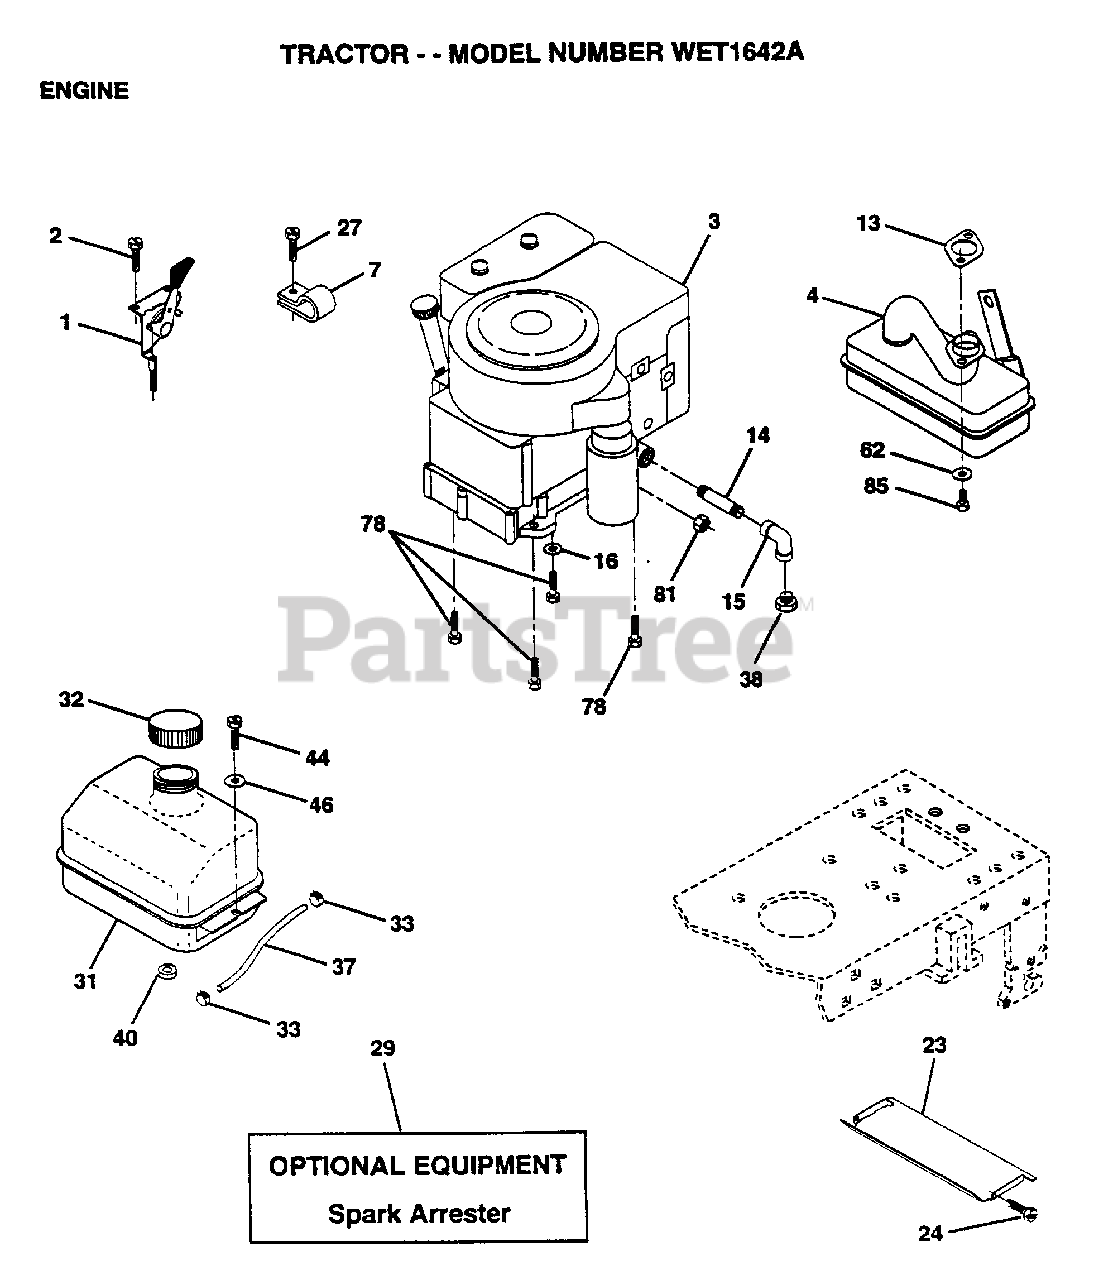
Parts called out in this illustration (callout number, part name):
2	SCREW LT
4	MUFFLER
7	CLAMP.TUBE.DBL.EN
13	GASKET MUFFLE TEC
14	PIPE NIPPLE
15	ELBOW
16	LOCKWASHER
23	HEAT SHIELD
24	SCREW
27	SCREW.10-24X1/2
31	TANK.FUEL.LT.
32	CAP ASM FUEL
33	HOSE CLAMP
37	LINE FUEL
44	SCREW HEX CRT
46	WASHER
62	LOCKWASHER
78	SCREW
81	NUT
85	SCREW HEX HD CAP
